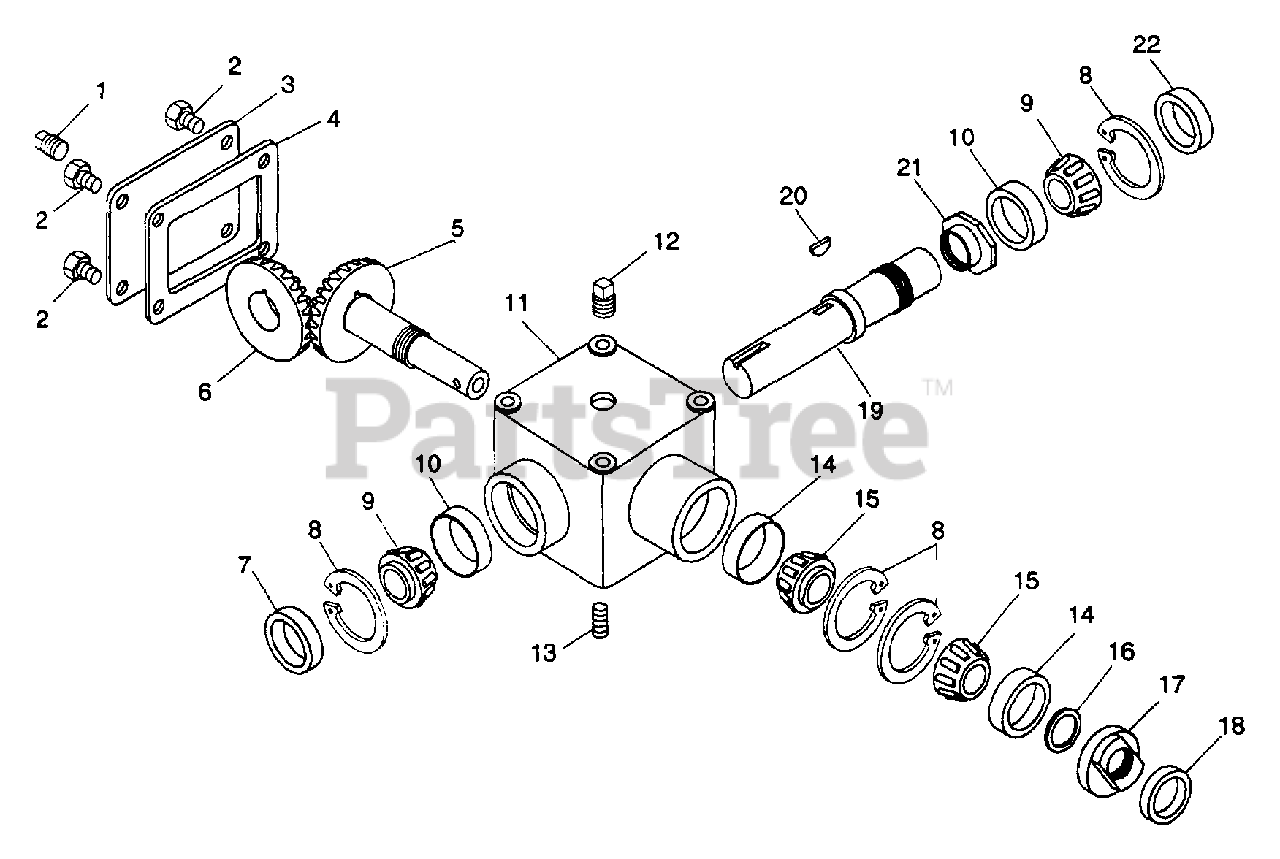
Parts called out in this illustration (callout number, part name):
1	PLUG-LEVER
2	BLT-HEX .31-18X.63 PL GR 2
5	BEVEL PINION SHAFT
6	BEVEL GEAR
8	RG-RTNG-INT 2.000X.062
9	BRG-CONE 1.0X.58
10	BRG-CUP1.980X.420
11	HOUSING
12	VENT PLUG
13	PLUG-DRAIN
14	BRG-CUP 1.980X.420
15	BRG-CONE 29MMX.58
16	O-RING 1.125X1.312X.093
17	STAKE NUT
18	SEAL 1.987 X1.500 X.313
19	OUTPUT SHAFT
20	KEY-WDRF .25X.875X.375 SAE A
21	STAKE NUT
22	SEAL 1.000X1.980X.250
